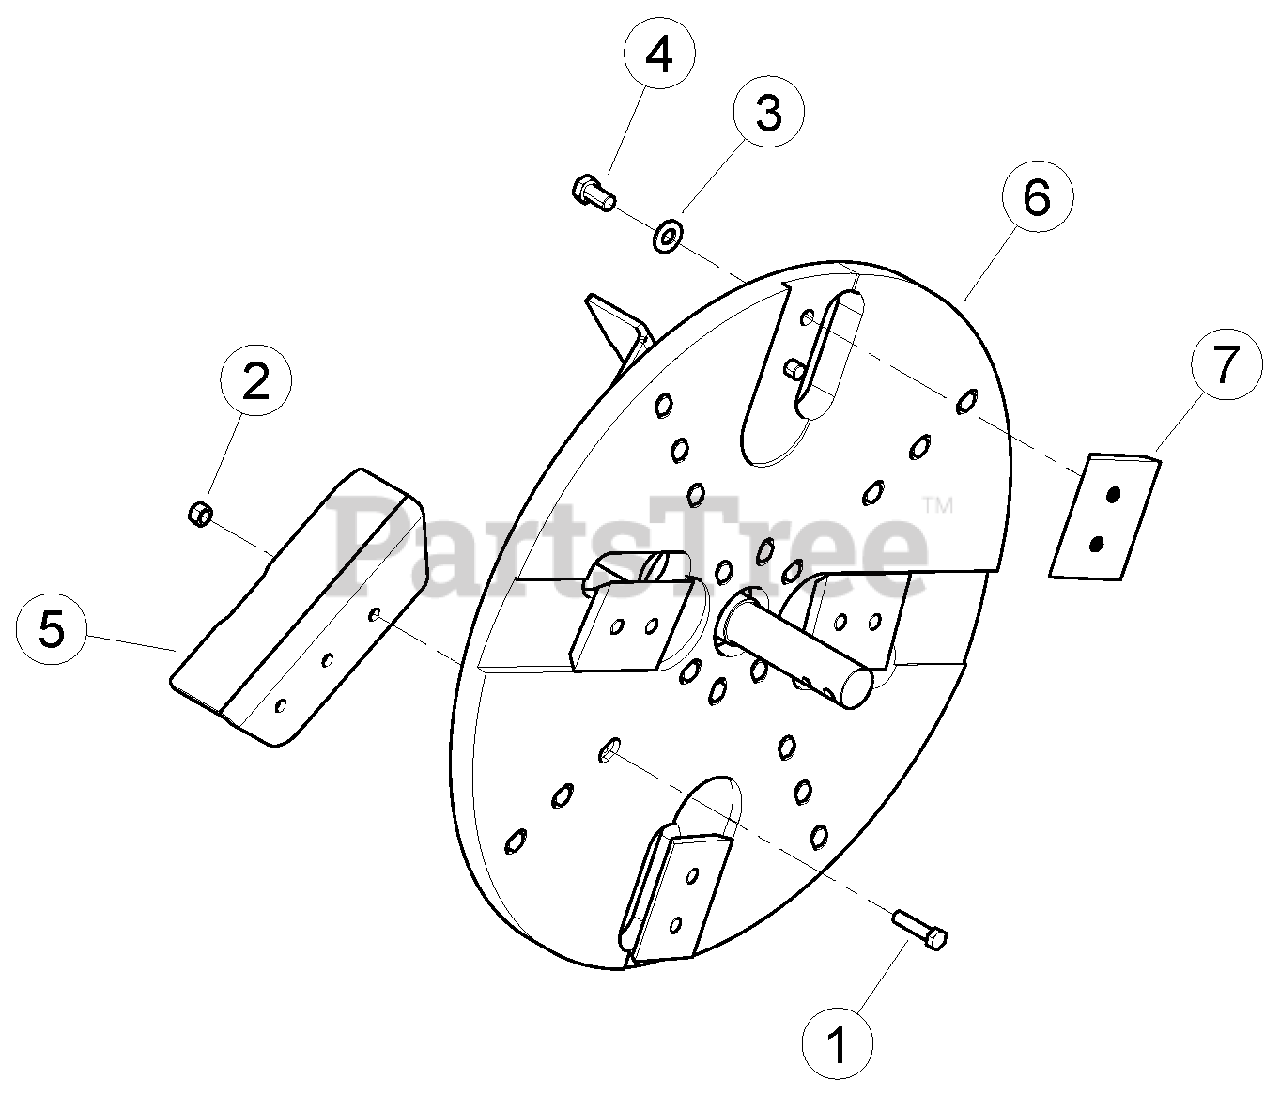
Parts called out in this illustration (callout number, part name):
1	BOLT, 1/2-13 X 2 GR5 HEX CAPSCREW
2	NUT, 1/2-13 GR5 CENTERLOCK GRB
3	WASHER, 5/8 SAE HARDENED
4	BOLT, M16 X 2.0 X 30 HEX HD W/ PATCH
5	KIT, BIG CHIPPER FORMED PADDLES
6	ASSEMBLY 9" CHIPPER ROTOR
7	KIT, CHIPPER BLADE
